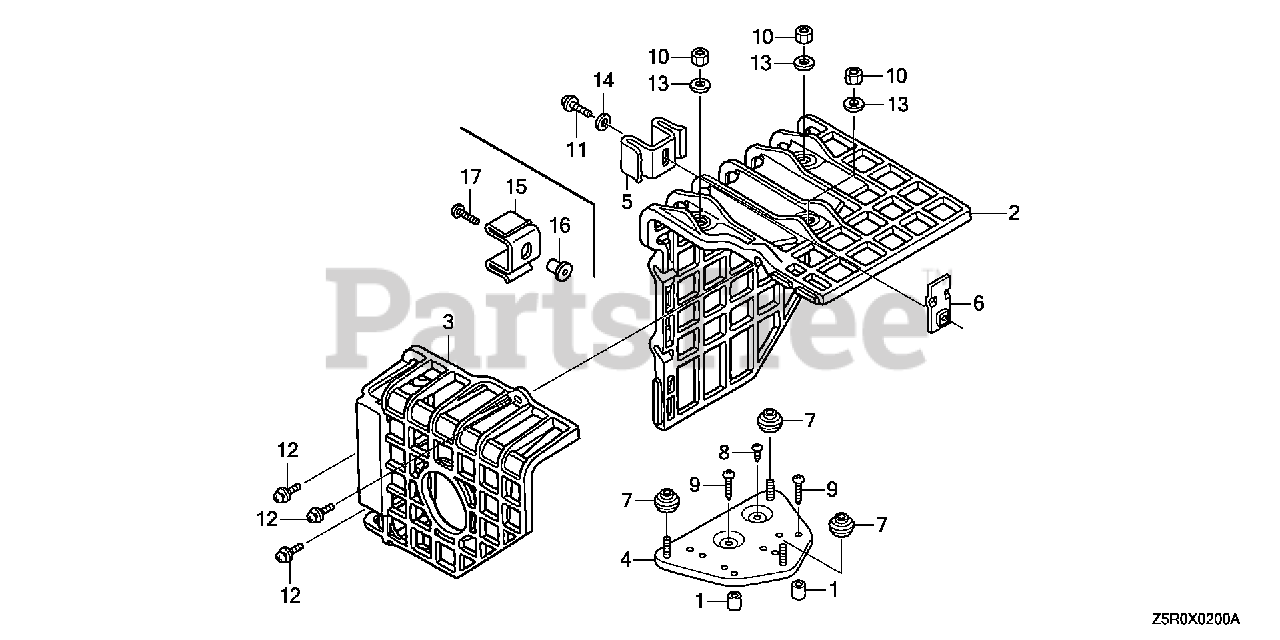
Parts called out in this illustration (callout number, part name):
1	COLLAR, AIR CLEANER HOUSING
2	COVER, MUFFLER
3	COVER, RR. MUFFLER
4	BASE, MUFFLER COVER
6	PLATE, SET
7	SPACER, MUFFLER COVER
8	SCREW, TAPPING (5X8)
9	SCREW, TAPPING (5X25)
10	NUT, HEX. (5MM)
11	SCREW-WASHER (5X12)
12	SCREW-WASHER (6X20)
13	WASHER, PLAIN (5MM)
14	WASHER, SPRING (5MM)
15	STAY, MUFFLER COVER
16	COLLAR, FAN COVER (Honda Code 5580527). (N/A: SEE ASSEMBLY)
17	SCREW, TAPPING (6X25)
